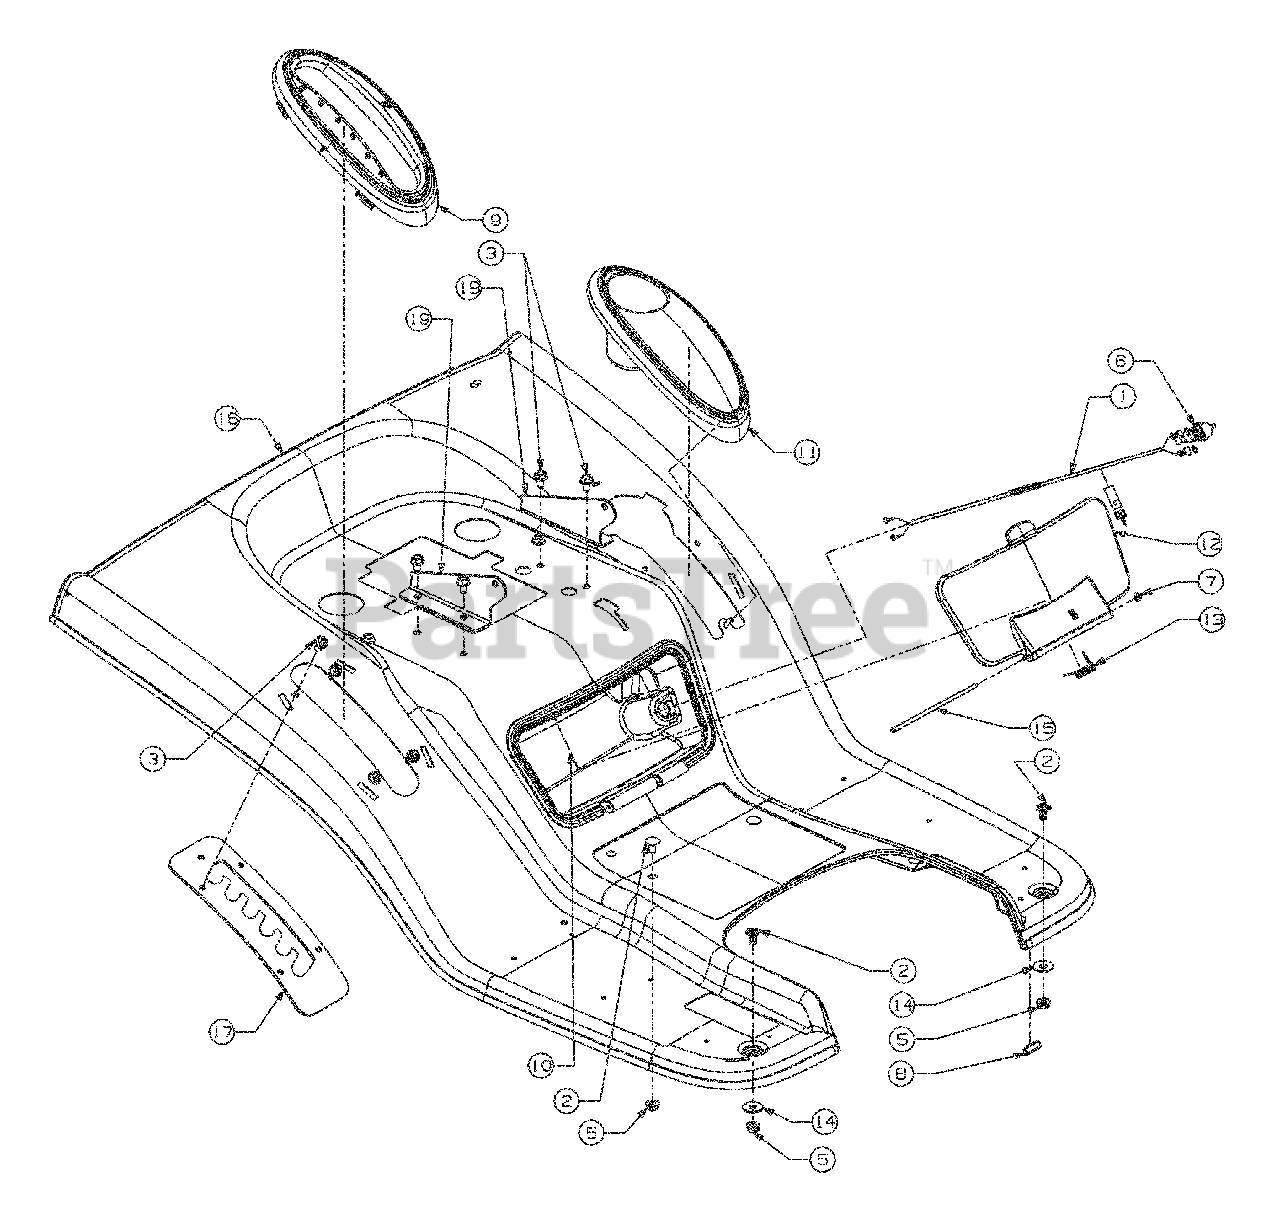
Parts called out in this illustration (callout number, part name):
1	HARN ASM:500:POWER OUTLET
2	BOLT:CRG:5/16-18:.62:GR1
3	SCR:TT:5/16-18:0.625:HXINDWSH
5	NUT:FLGLK:5/16-18:GR5:SD LK
6	ELEC:POWER OUTLET
7	PUSH CAP: .19 ROD
9	CVR:LIFT LEVER
11	CVR:W/CUP HOLDER
12	CVR:TOOLBOX
13	SPR:TORSN:.23 ID
14	FL-WASH .344 X 1.00 X .063 HDN
